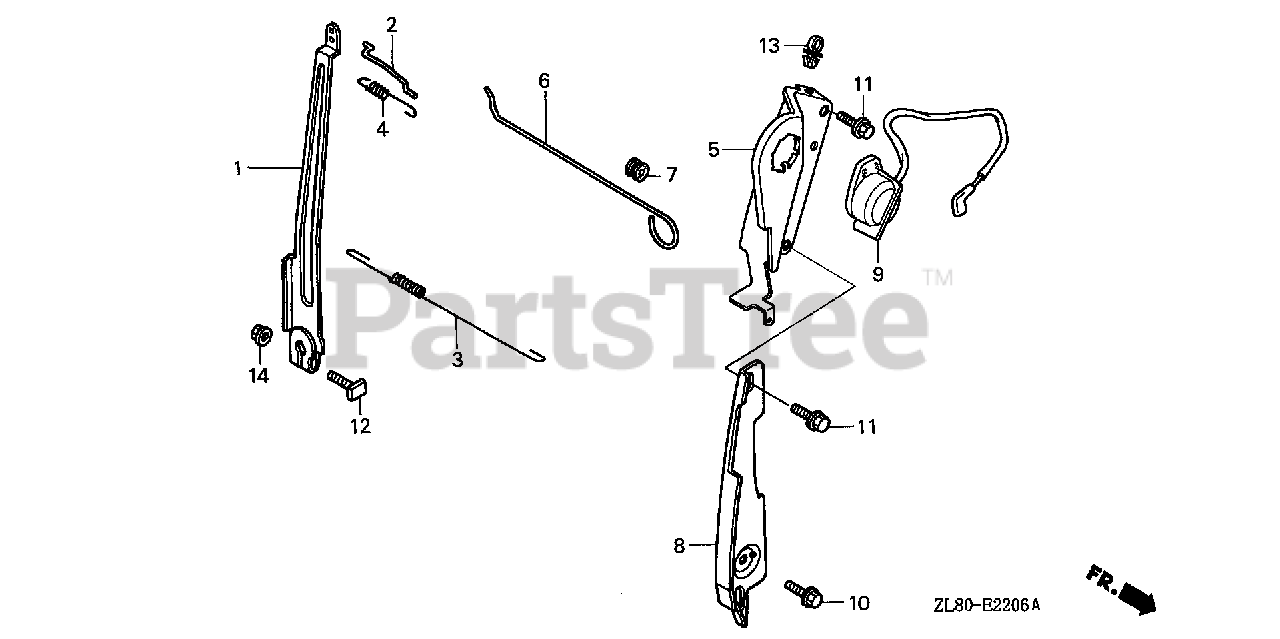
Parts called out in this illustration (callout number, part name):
1	ARM, GOVERNOR
2	ROD, GOVERNOR
3	SPRING, GOVERNOR
4	SPRING, THROTTLE RETURN
5	BASE, CONTROL
6	ROD, CHOKE CONTROL
7	GROMMET, CHOKE ROD
8	PLATE, SIDE
9	SWITCH ASSY., ENGINE STOP
10	BOLT, FLANGE (6X12) (CT200)
11	BOLT, FLANGE (6X14) (CT200)
12	BOLT, GOVERNOR ARM
13	CLIP A, CABLE (3.8MM BLACK) (NIFCO)
14	NUT, FLANGE (6MM)
